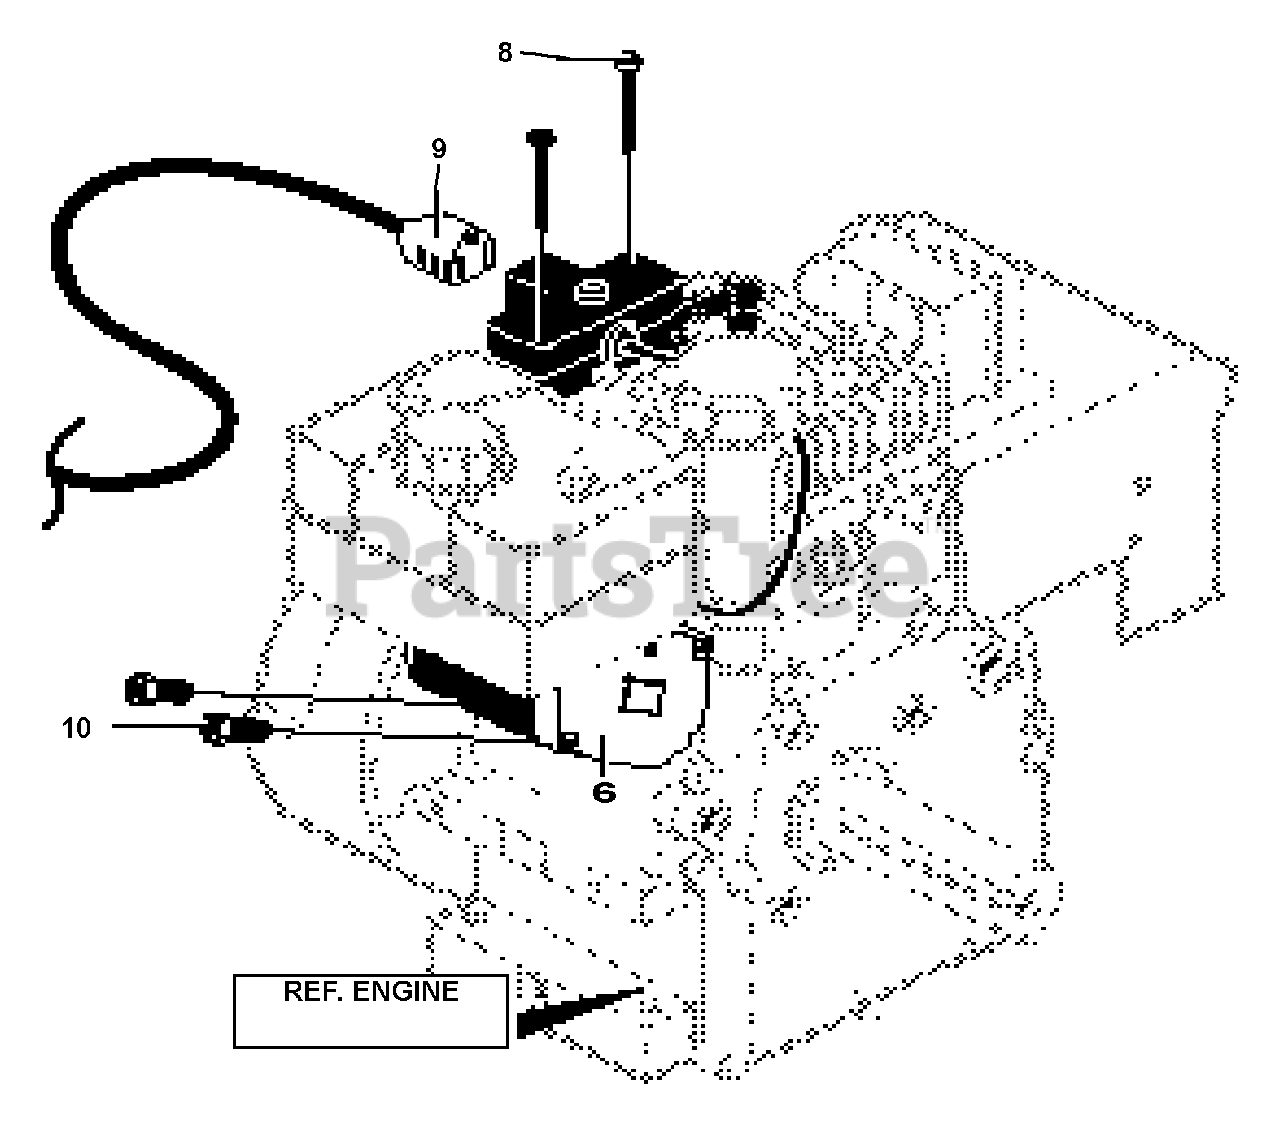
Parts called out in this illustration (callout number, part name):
6	MOTOR, STARTER
7	SCREW, 1/4-20X .50
8	SCREW, #6-32X2.50
9	CORD, STARTER
